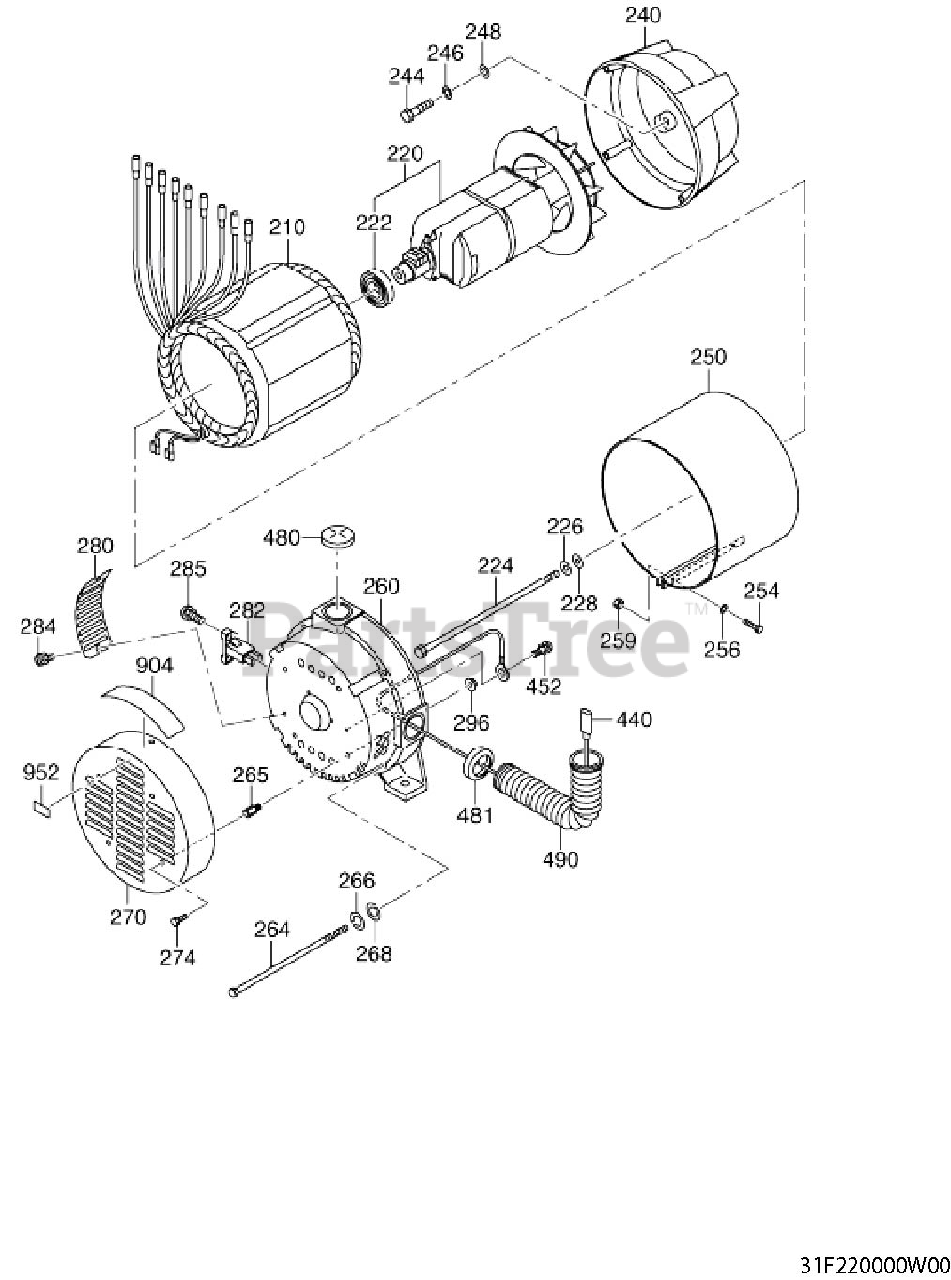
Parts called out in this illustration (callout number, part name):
226	SPRING WASHER
228	WASHER
240	FRONT BRACKET
246	SPRING WASHER
248	WASHER
260	REAR COVER
266	SPRING WASHER
268	WASHER
270	END COVER
274	FLANGE BOLT
282	BRUSH HOLDER
284	SCREW AND WASHER AY
285	SCREW AND WASHER AY
296	FLANGE NUT
452	SCREW
904	LABEL, SPEC
